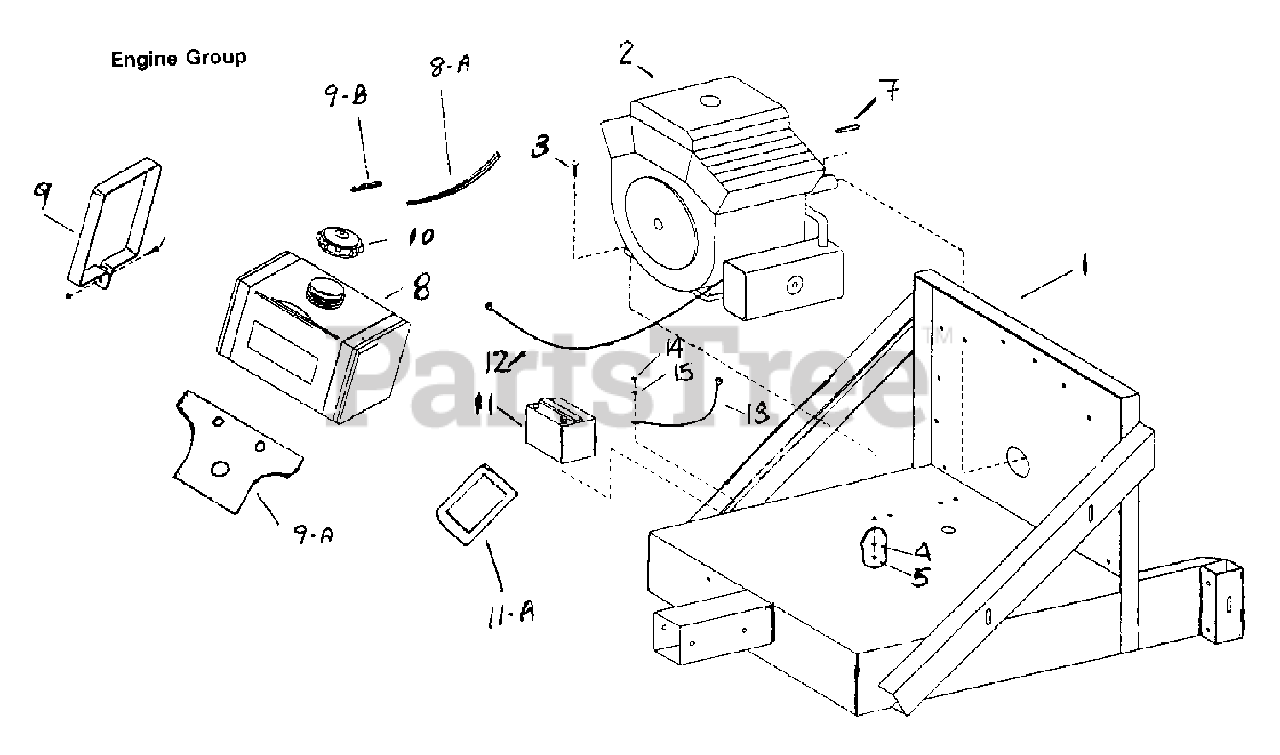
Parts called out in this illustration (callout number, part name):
1	Engine Base
2	* 20HP Kohler Command Engine
3	3/8 x 2" Hex Bolt (Motor Mount Bolt)
3	3/8 x 1-3/4" Hex Bolt (Motor Mount Bolt)
4	3/8 Lock Washer
5	3/8 Hex Nut
7	5/8-18 x 2" Impeller Bolt & Key Group
8	Fuel Tank, 6 Gal.
8A	Hose, Rubber Fuel 1/4" x 10" Length
9	Fuel Tank Strap
9A	Gas Tank Mount
9B	Inline Fuel Shutoff Valve
11A	Battery Box
12	Battery Cable - 32SS (Positive)
13	Battery Cable - 16SS (Ground)
14	3/8 Hex Nut (secures ground cable to engine base)
15	3/8 Lock Washer
